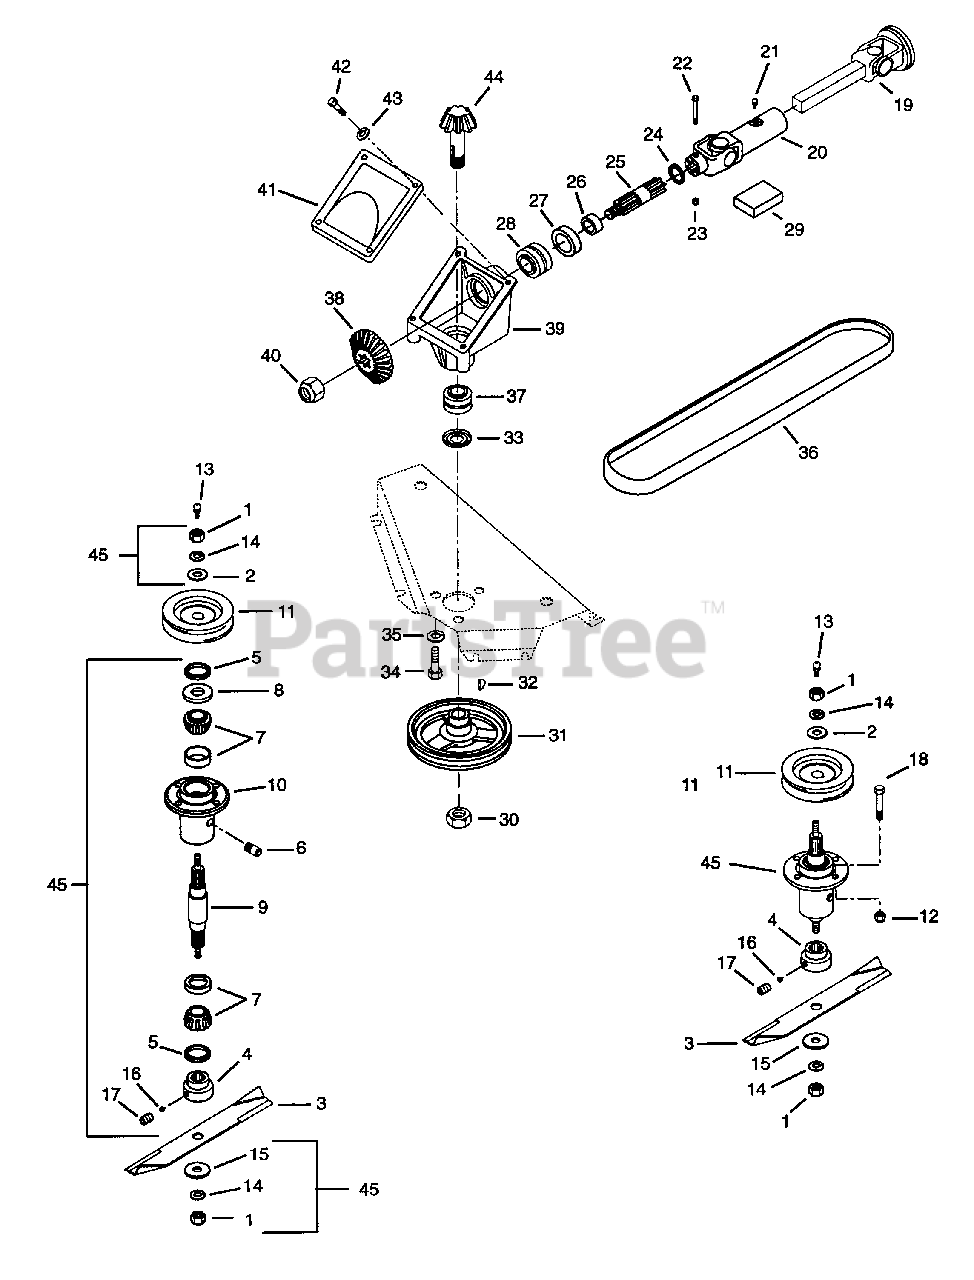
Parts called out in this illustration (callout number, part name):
1	Nut-Hex .625-11 Grade 2
2	Washer-Flat-Steel .687 x 1.312 x .150
3	Blade
5	Seal 1.987 x 1.375 x .313
6	Relief Fitting - Grease
7	Assembly, Bearing Cup & Cone
8	Washer-Hardened-Thrust 1.007 x 1.542 x .062
9	Shaft, Spindle
10	Bearing Housing
12	Nut-Locking-Nylon .375-16 Grade 2
13	Fitting-Lube 1/8
14	Washer-Locking .625 x .156
15	Washer-Flat .640 x 1.81 x .250
17	Screw-Set .25-20 x .25
18	Bolt-Hex .38-16 x 1.25 Grade 5
19	Shaft, Prop Square Bar
20	Joint, U Female Eng
21	Fitting, Lube .25-28
22	Bolt-Hex .25-20 x 2.00 Grade 5
23	Nut-Locking-Nylon .250-20 Grade 2
24	Ring-Retaining 1.106 x .95
25	Shaft
26	Bushing Flange 1.00 x 1.25 x 1.25
27	Seal 1.250 x 1.983 x .250
28	Bearing-Assembly 1.000 x 1.980 x 1.243
29	Kit, Repair U-Joint
30	Nut-Hex-Jam .750-10
31	Sheave, Drive
32	Key-Woodruff .19 x .63
33	Seal 1.250 x 1.691 x .310
34	Bolt-Hex .50-13 x 1 Grade 5
35	Washer-Lock .50 Reg.
36	V-Belt A-Section 33.25 x .504
37	Bearing-Assembly .75 x 1.781 x 1.499
38	Gear, Bevel
39	Casting, Gear Box
40	Nut-Locking-Nylon .75-10 Grade 2
41	Cover, Gear Housing
42	Bolt-Hex .25-20 x .50
43	Washer-Lock .250 Reg.
44	Shaft, Gear Pinion
45	Service Kit Spindle Assembly
